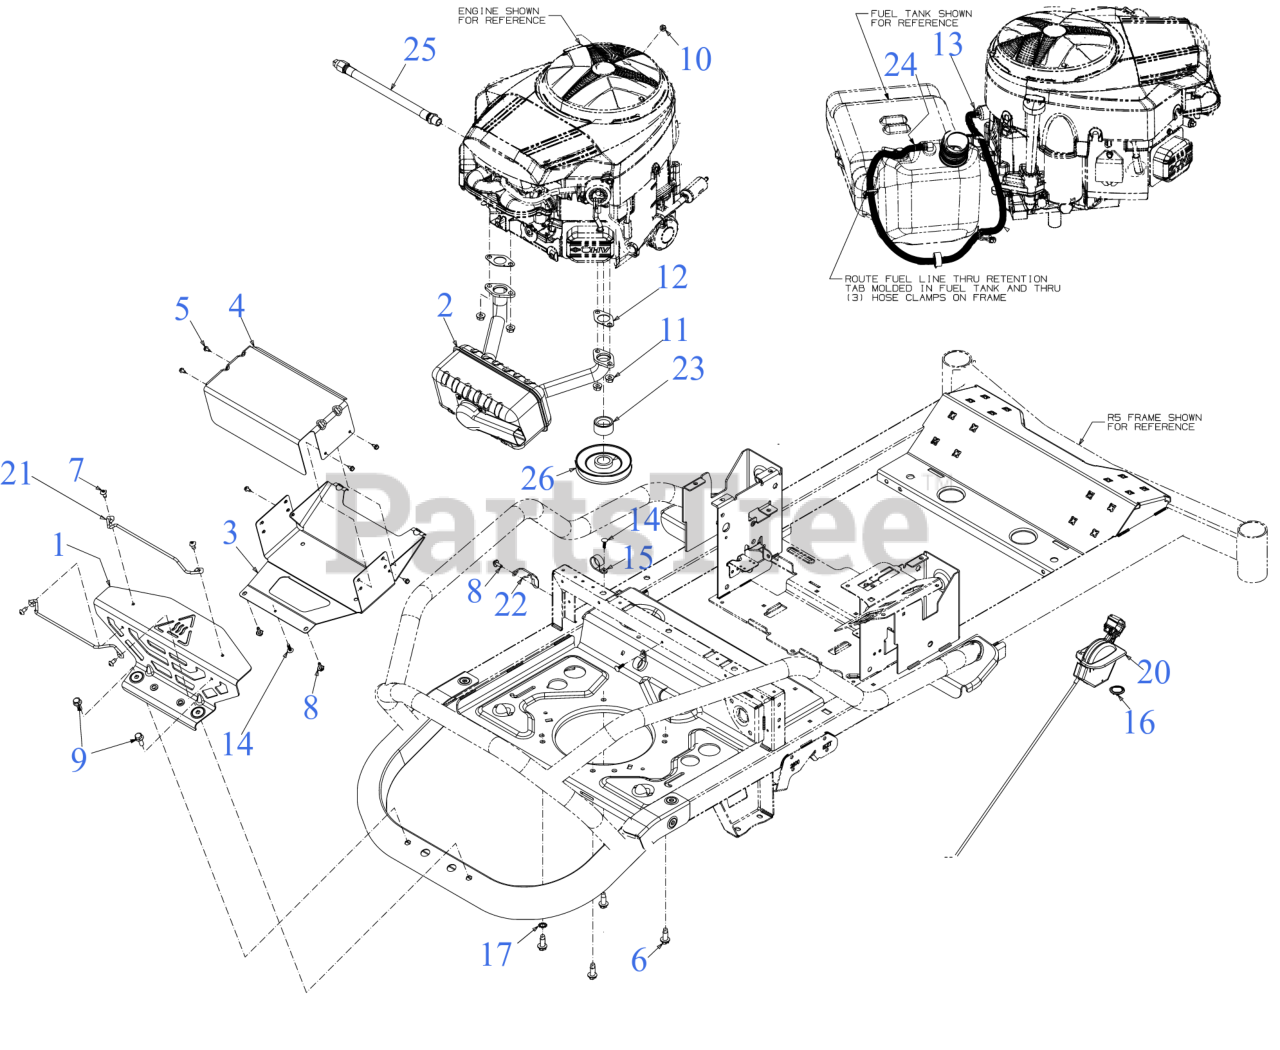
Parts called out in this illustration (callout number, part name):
1	MUFFLER COVER (REAR) (BLACK)
2	EXHAUST MUFFLER (B&S TWIN)
3	MUFFLER SHIELD (LOWER)
4	MUFFLER SHIELD (TOP)
5	HEX SCREW AB-TAP #10 x .50
6	SCREW 3/8-16 x 1
7	SCREW 1/4-20 x .5
8	SCREW M6-1 x .625
9	SCREW 5/16-18 x .875 GR5
10	HEX NUT 1/4-20
11	HEX FLANGE NUT M8X
12	MUFFLER GASKET
13	HOSE CLAMP 1/20
14	RATCHET CLIP (.188 x .85)
15	DRAIN HOSE CLAMP
16	CHOKE PLUG
17	LOCK WASHER 3/8
20	THROTTLE/CHOKE CABLE 38.0LG
22	HOSE GUIDE
23	ENGINE PULLEY SPACER
24	FUEL HOSE LOW PERMEATION 45"
25	OIL DRAIN HOSE (11.26" 3/8 NPT)
26	TRANSMISSION DRIVE PULLEY
